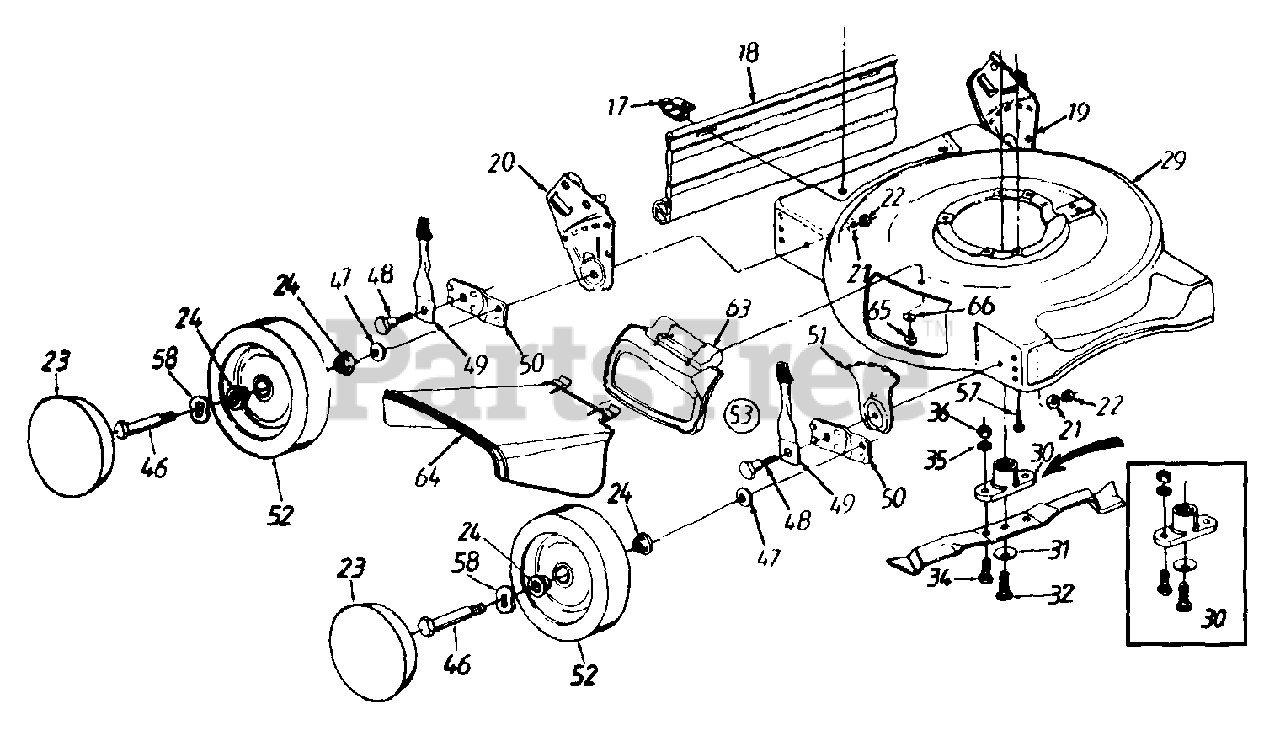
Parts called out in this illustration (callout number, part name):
17	Hinge Clip
18	Rear Flap (702E)
19	Handle Bracket Ass'y. - L.H. (702E)
20	Handle Bracket Ass'y. - R.H. (702E)
21	Bell-Wash. .39" I.D. x 1.38"
22	Hex Nut 3/8-16 Thd.
23	Hub Cap
24	Bearing
31	Bell-Wash. .46" I.D.
32	Hex Bolt 7/16-20 x 1.5" Lg.
34	Hex Bolt 3/8-24 x 1" Lg.
35	L-Wash. 3/8" I.D.
36	Hex Nut 3/8-24 Thd.
47	Bell-Wash. .400" I.D. x .88"
48	Shld. Bolt .50" Dia. x .357"
49	Spring Lever Ass'y. w/Knob
51	Height Adj. Plate
52	Wheel Ass'y. Comp.
53	Height Adj. Ass'y. Comp. - R.F. & L.R.
57	Hex L-Wash. Hd. Scr. 3/8-16 x 1.0" Lg.
58	Wave Washer .51" I.D.
63	Mulching Plug (702E)
64	Chute Deflector
65	Bell-Wash. 1/4" I.D.
66	Hex Wash. Hd. TT-Tap Scr. 1/4-20 x .5" Lg.
